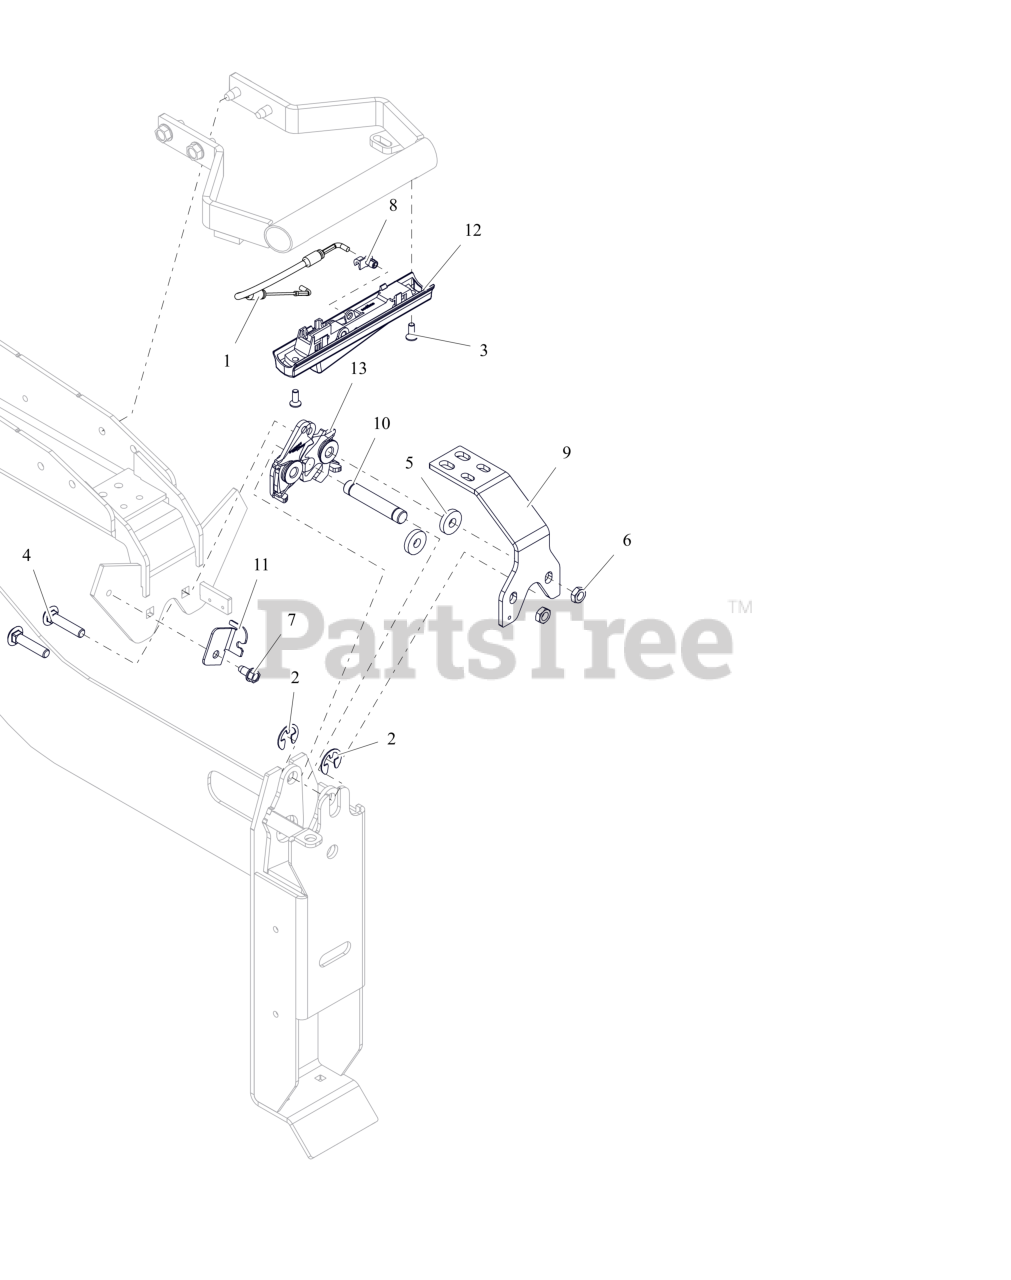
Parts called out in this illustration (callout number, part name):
1	CABLE, HOOD RELEASE
2	RG-RTNG-EXT .438X.035
3	SCR, FLCSKH M5-0.8X14 GR10.9 ROHS
4	BLT,RHSN .31-18X1.50 G5 ZCC
5	WSHR, FLT .328X.870X.179 ZCC
6	NUT-LK-CTR-JAM .312-18 GB ZCC
7	SCR-TAP .25-20X.50 HWH ZCC
8	CLIP, RETAINER
9	BRKT, LATCH MTG (BLUE)
10	ROD, LATCHING
11	RETAINER, CABLE (BLACK)
12	HANDLE, SQUEEZE ACTUATOR
13	LATCH, PUSH TO CLOSE
